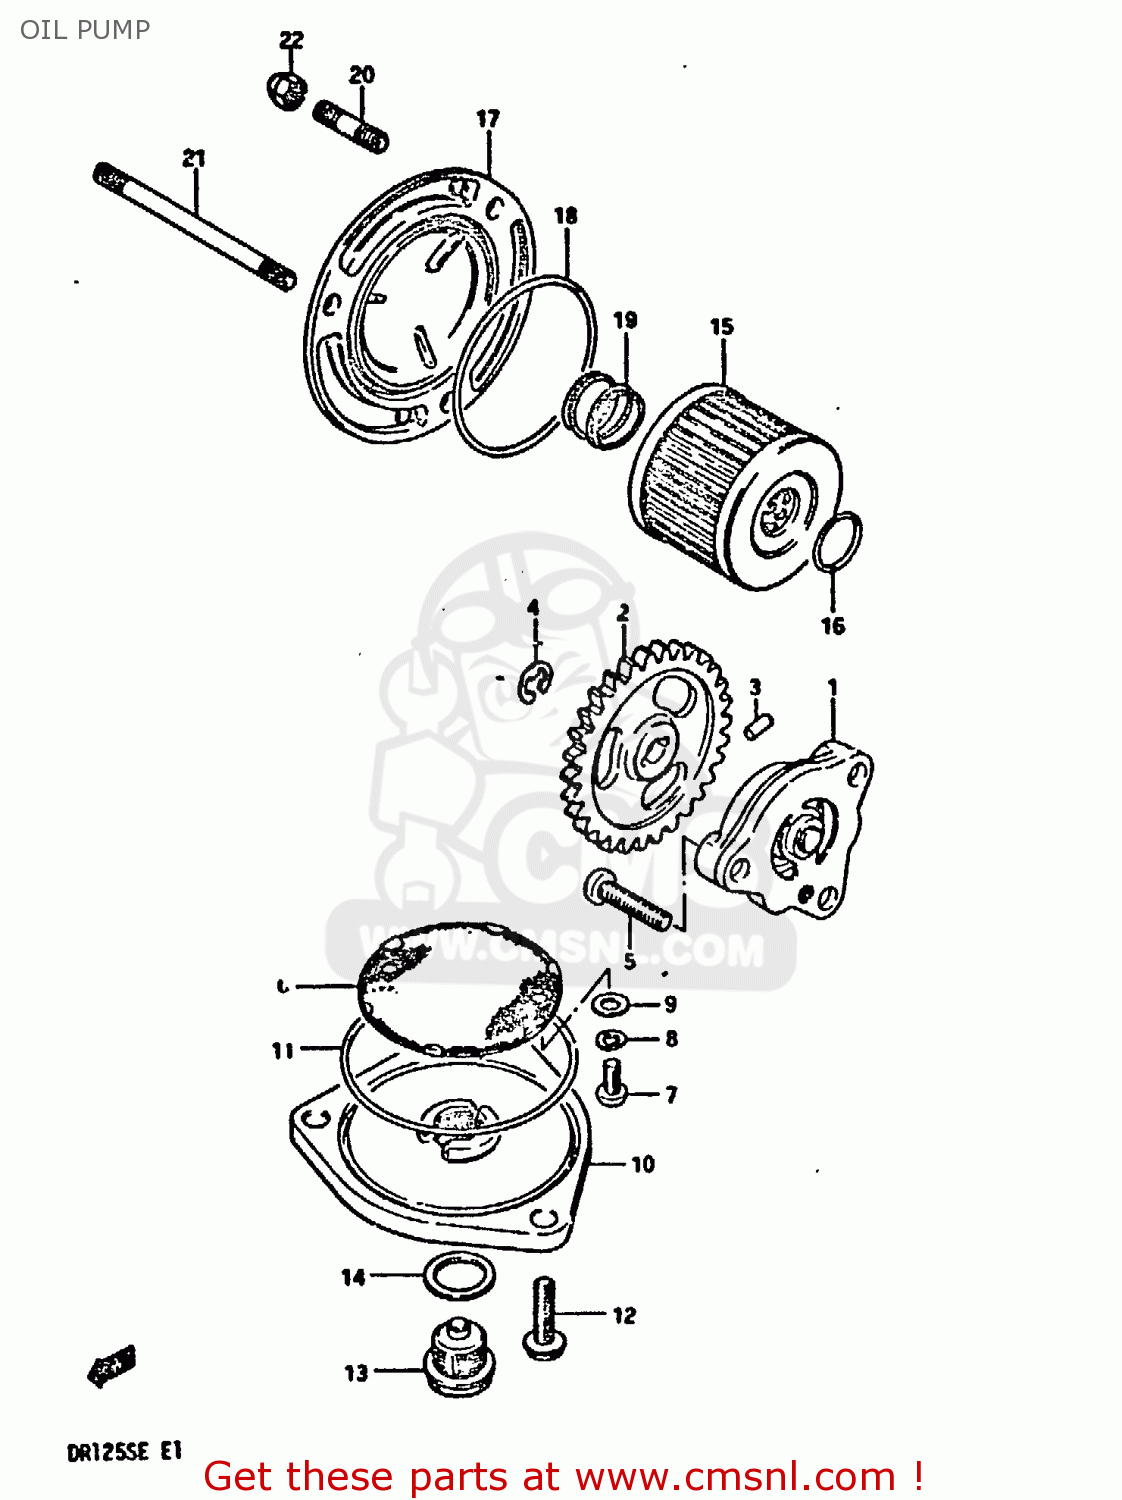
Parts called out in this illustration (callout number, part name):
1	PUMP ASSEMBLY,OIL
2	GEAR,ENG OIL PUMP DRIVEN(NT:30
3	PIN(2.5X11.8)
4	E RING 6MM
5	SCREW
6	STRAINER,ENGINE OIL
7	SCREW
8	LOCK WASHER
9	WASHER
10	CAP,OIL STRAINER
11	O RING(D:2.4,ID:60.5)
12	BOLT (6X20)
13	PLUG
14	GASKET(14X19.2X2) (NAS)
15	FILTER ASSY,ENGINE OIL
16	O RING(D:1.9,ID:13)
17	CAP,OIL FILTER
18	O RING(D:2.4,ID:52.6)
19	SPRING
20	STUD 6X12
21	STUD BOLT, 6X8
22	NUT 6MM
